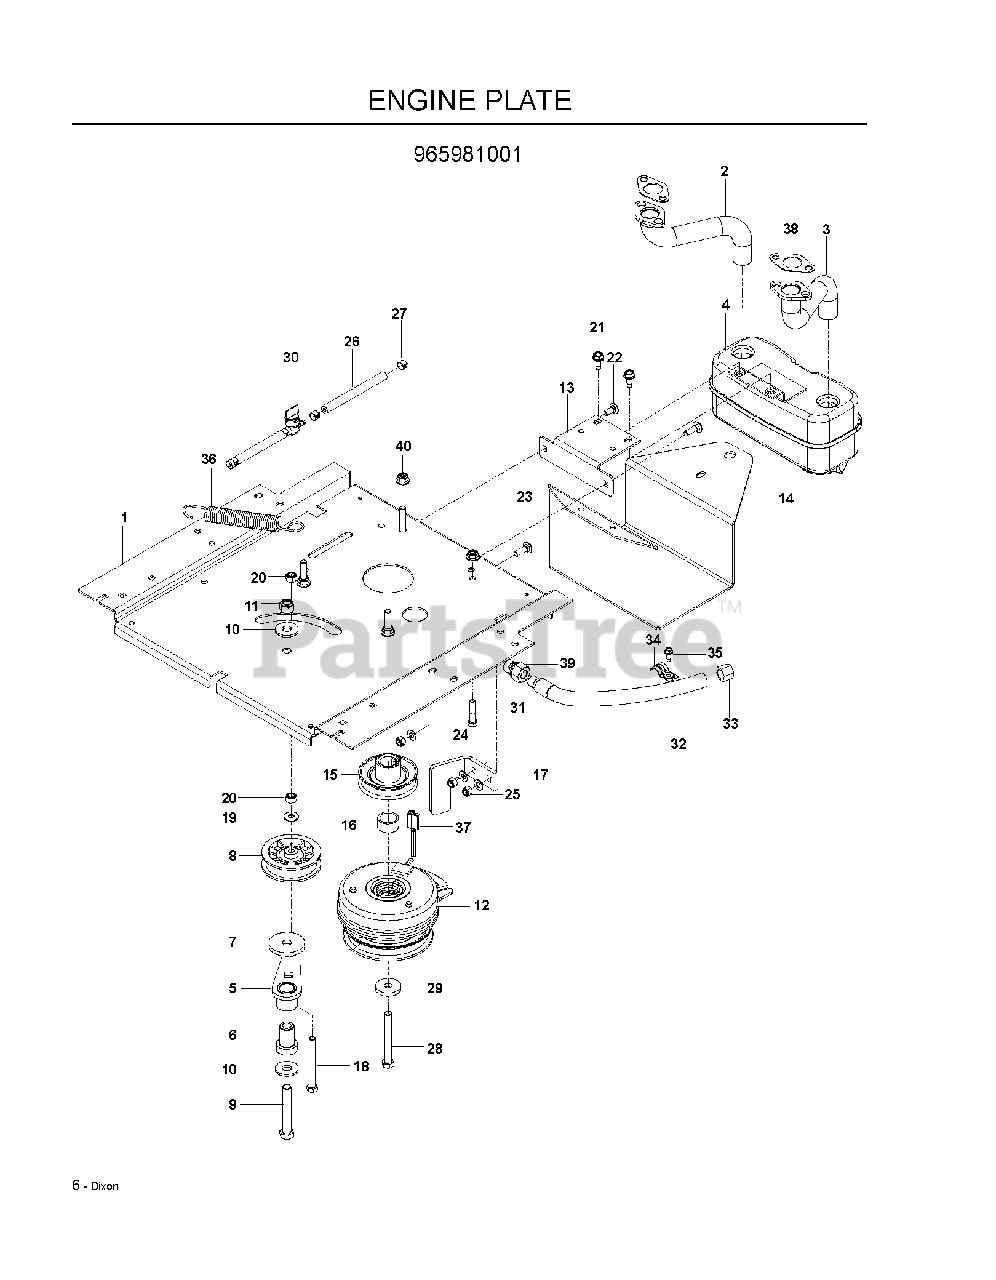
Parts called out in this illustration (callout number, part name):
1	PLATE ENGINE, BLACK
2	EXHAUST TUBE
3	EXHAUST TUBE
4	MUFFLER ASM TWIN
5	IDLER ARM WELDMENT
6	IDLER SPINDLE
7	HEAVY WASHER
8	PULLEY, IDLER
9	HCS 1/2C X 3 1/4
10	WASH USS FLAT 1/2
11	NUT 1/2-13 HEX NYLOC ZD
12	CLUTCH, 105 FT-LBS
13	BRACKET, MUFFLER, BLACK
14	GUARD, MUFFLER, BLACK
15	PULLEY, ENGINE
16	T & B SPACER
17	STOP, CLUTCH, BLACK
18	HCS 3/8-16X3 1/2 GR5
19	WASHER 5/16 FLAT
20	NUT 3/8-16 NYLOC
21	BOLT 5/16-18 X 3/4
22	BOLT 5/16C X 3/4" CARRIAGE
23	RHSNB 5/16C X 1
24	FLAT WASHER 5/16 SAE
25	NUT 5/16 NYLOC
26	FUEL LINE 5"
27	HOSE CLAMP
28	HCS 7/16-20X3-1/2 GR 5 ZN
29	CLUTCH, WASHER
30	FUEL VALVE
31	HHFS 3/8-16 X 1.0 THD FORMING
32	OIL DRAIN HOSE
33	DRAIN CAP
35	SCREW 1/4 X 5/8
36	SPRING, DECK DRIVE
37	CLUTCH HARNESS
38	EXHAUST GASKET - KAW
39	ADAPTER, OIL DRAIN
40	5/16-18 NYLOC FLANGE NUT
